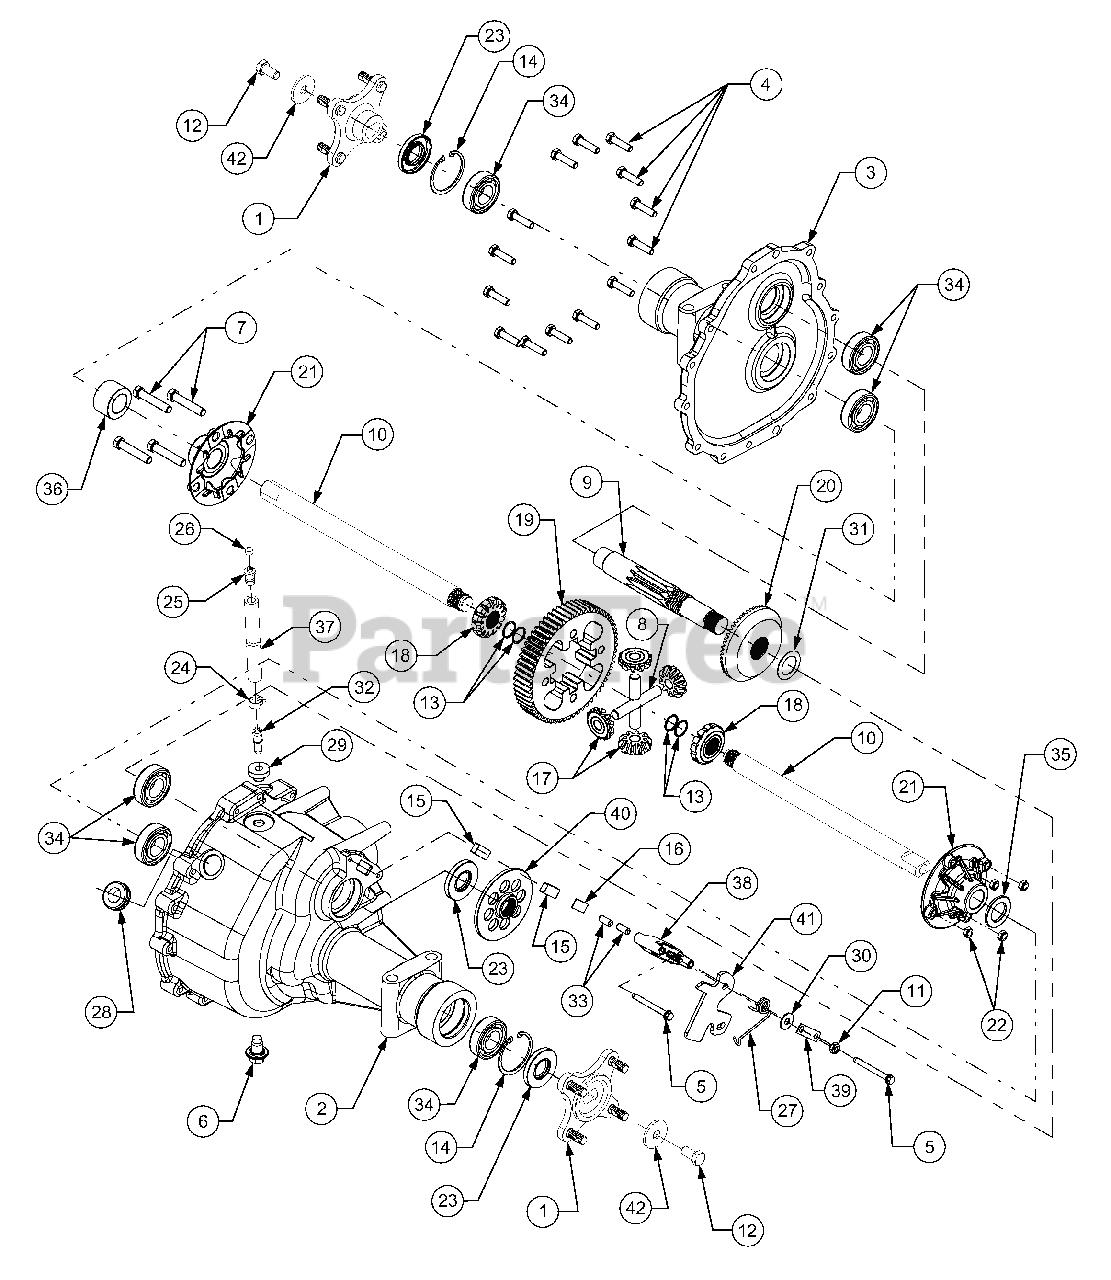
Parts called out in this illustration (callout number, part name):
1	Hub Assembly, Wheel
2	Housing, RH Transmission
3	Housing, LH Transmission
4	Screw, Hex Cap Lock, 5/16-18 x 1.25 GR5
5	Screw, Hex Wash Hd. Tapp, 1/4-20 x 2.375
6	Screw, Plug, M14 x 1.5 x .827
7	Screw, Hex Cap Lock, 3/8-16 x 2.0 GR5
8	Shaft, Cross, .50 x 3.005
9	Shaft, Output, 9T
10	Shaft, Axle
11	Nut, Hex Nylon Lock, 5/16-24
12	Screw, Hex Cap Lock, 3/8-16 x .75 GR5
13	Ring, Retaining
14	Ring, Retaining
15	Pad, Brake
16	Plate, Puck
17	Gear, Miter, 10T
18	Gear, Miter, 14T
19	Gear, Differential Spur, 60T
20	Gear, Bevel, 54T
21	Housing, Differential w/Thru Holes
22	Nut, Hex Insert Jam GR5, 3/8-16
23	Seal, Oil, 1.0 x 2.047 x .2755
24	Clamp, Hose
25	Vent, Plastic
26	Cap, Plastic Vent
27	Spring, Torsion
28	Grommet, Rubber, .75 x 1.063
29	Grommet, Rubber, .362 x .56
30	Washer, Flat, .343 x .88 x .062
31	Washer, Thrust, 1.007 x 1.542 x .03
32	Fitting, Tube
33	Pin, Brake Actuating
34	Bearing, Ball (6205-1)
35	Spacer, Axle, 1.007 x 1.665 x .141
36	Spacer, Axle, 1.007 x 1.665 x .989
37	Tube, Transmission Breather
38	Yoke, Brake
39	Bracket, Brake Anti Rotation
40	Disc, Brake
41	Arm, Brake Actuater
42	Washer, Flat, .39 x 1.5 x .134
